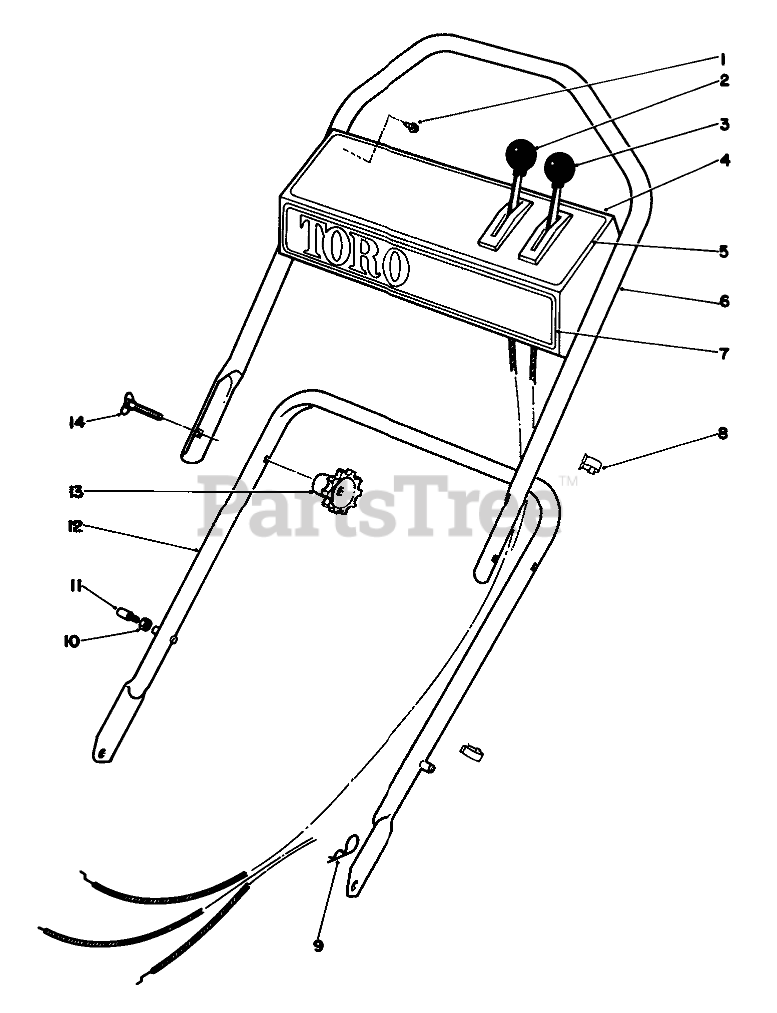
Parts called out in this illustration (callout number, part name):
1	SCREW-HWHTF
2	SERVICE THROTTLE CONTRO
3	SERVICE TRACT. CONTROL
4	Panel-Control (Incl. Ref. #5)
5	DECAL
6	Handle-Upper
7	Decal-Toro
8	BOWDEN CLIP
9	PIN-COTTER, HAIR
10	NUT-LOCK, NI
11	HANDLE PIN
12	LOWER HANDLE ASM
14	5/16-18 X 2 HNDLE SCREW
